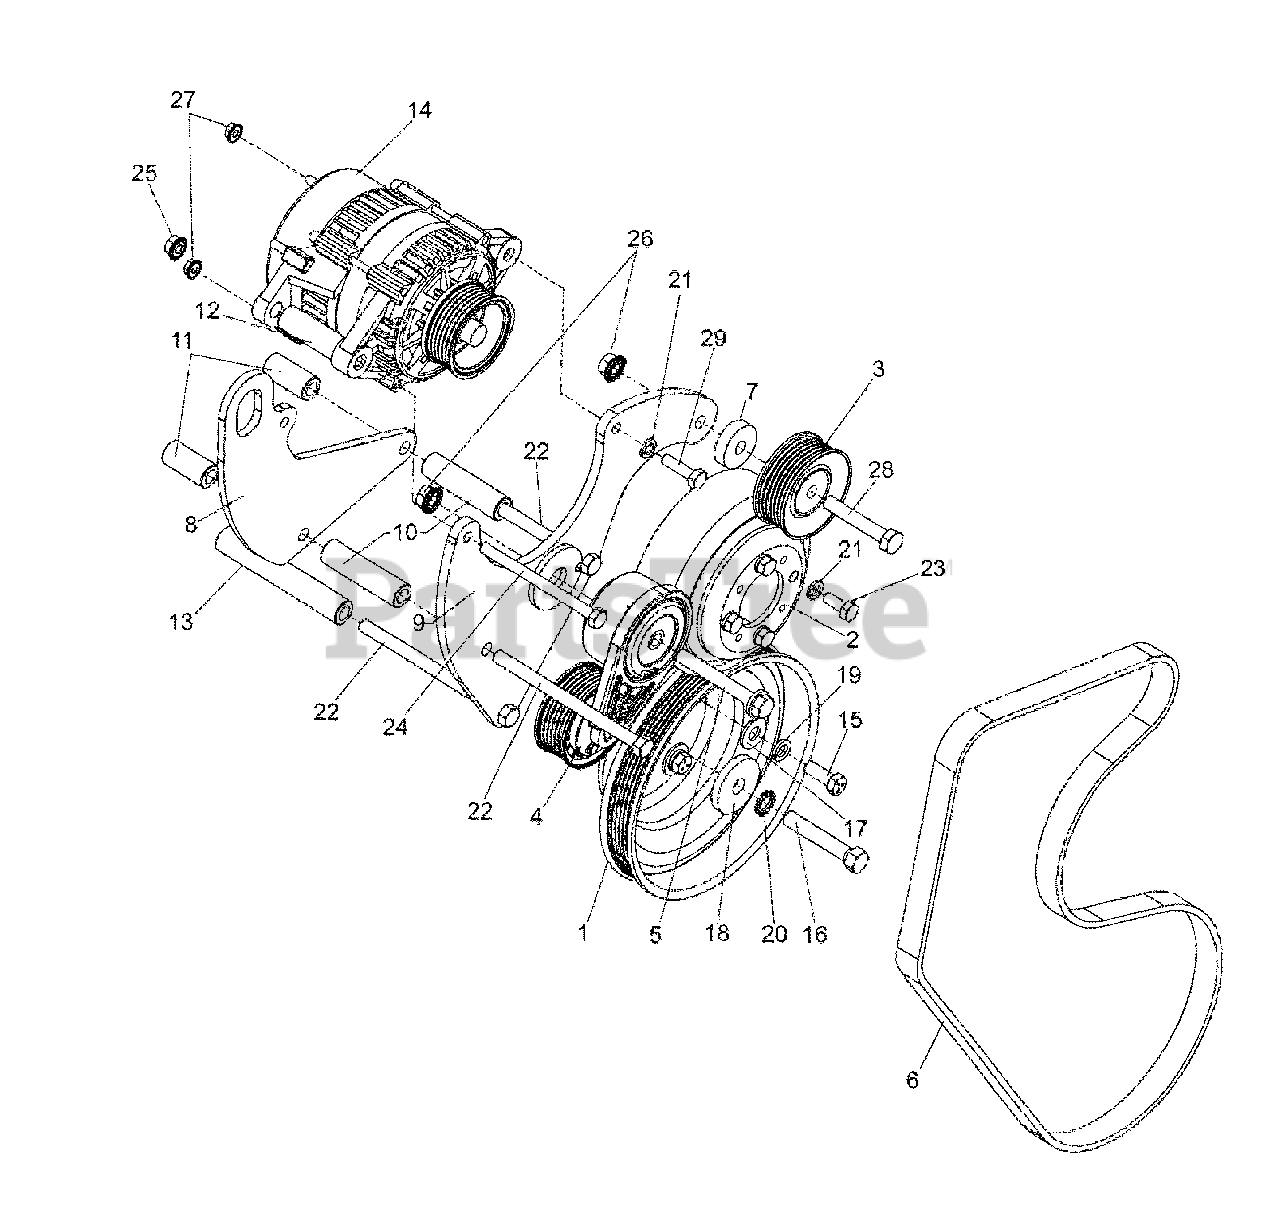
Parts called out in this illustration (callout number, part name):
1	PULLEY-CRANKSHAFT
2	PULLEY-WATER PUMP
3	PULLEY-IDLER
4	BELT-TENSIONER
5	BOLT
7	SPACER
8	PLATE
9	BRACKET
10	SPACER
11	SPACER
12	SPACER
13	SPACER
15	SCREW
16	BOLT
17	WASHER
18	WASHER
19	WASHER
20	WASHER
21	WASHER
22	BOLT
23	BOLT
24	BOLT
25	NUT
26	NUT
27	NUT
28	BOLT
29	BOLT
